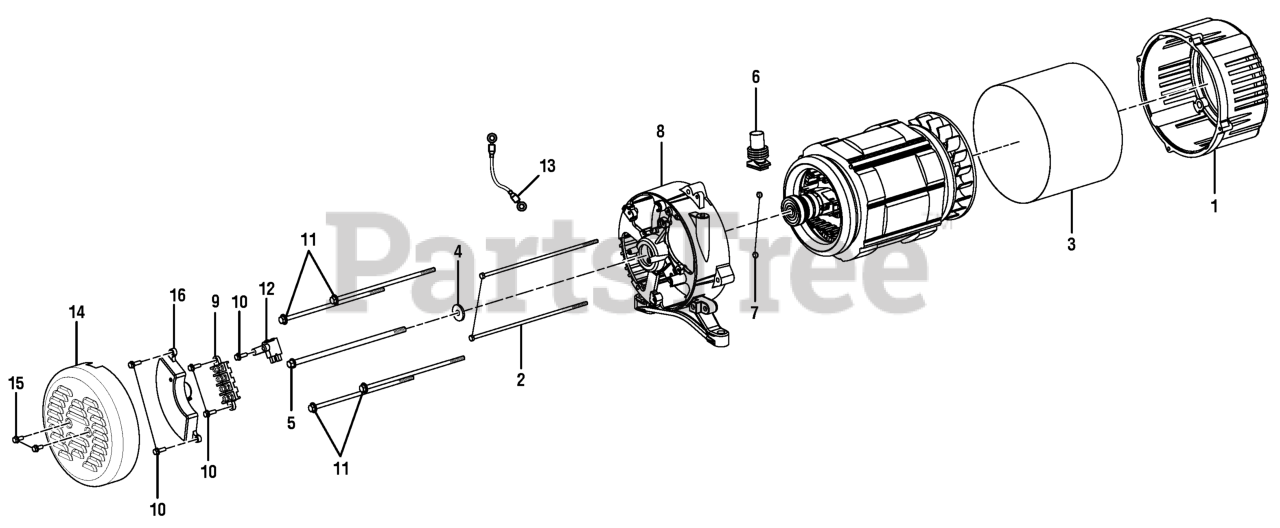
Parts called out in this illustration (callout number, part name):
1	ADAPTOR HOUSING
2	BOLT (M5, HEX HD.)
3	GENERATOR HEAD COVER
4	LOCK WASHER (5/16)
5	ROTOR BOLT (170 MM)
6	RUBBER BOOT
7	HEX NUT (M5)
8	BEARING HOUSING
9	TERMINAL BLOCK
10	BOLT (M5 X 16 MM)
11	STATOR BOLT (170 MM)
12	BRUSH ASSEMBLY
13	BONDING WIRE
14	BRUSH COVER
15	BOLT (M5 X 12 MM)
16	AUTOMATIC VOLTAGE REGULATOR
